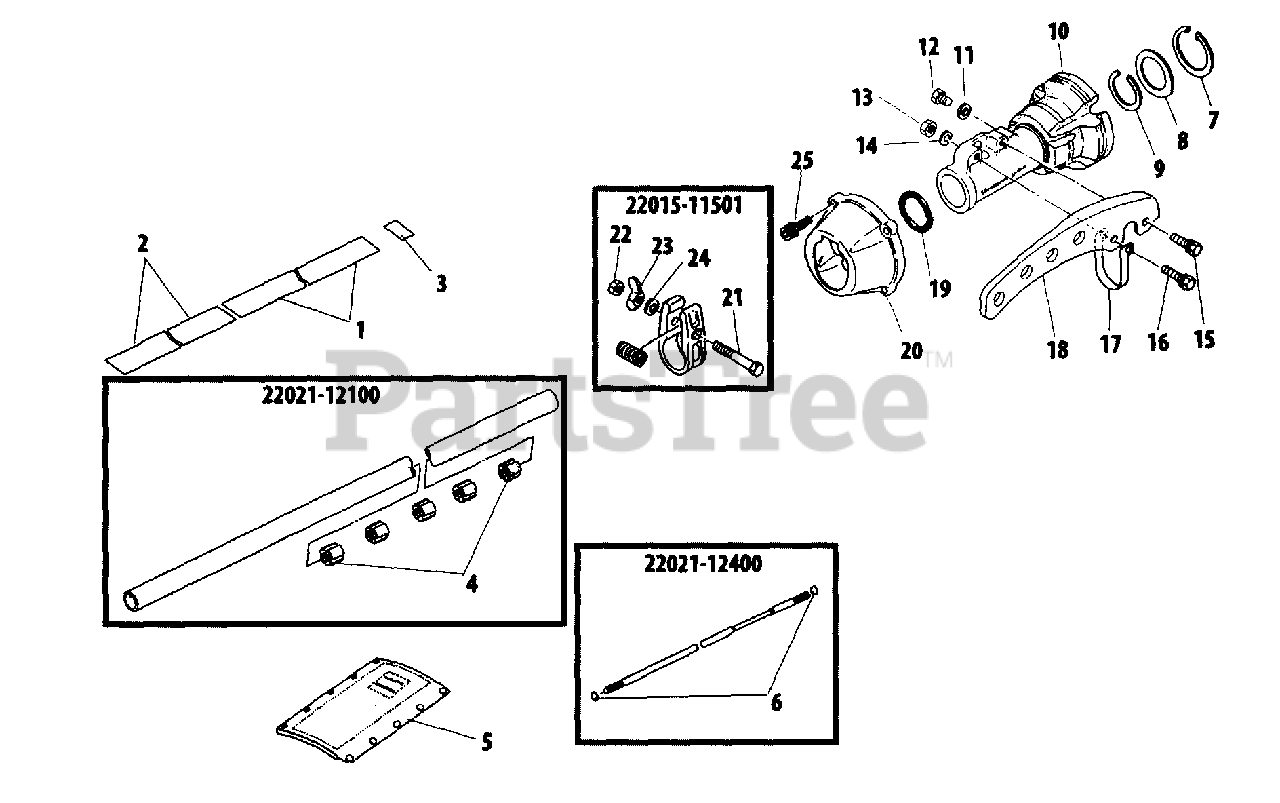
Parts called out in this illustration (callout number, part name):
1	LABEL - MODEL
2	LABEL, CAUTION
3	LABEL, HANDLE
4	BUSHING
5	PROTECTOR
6	STOPPER
7	RING, SNAP Ø40
8	STOPPER
9	RING, SNAP
10	CUSHION, AV
11	WASHER
12	BOLT M6×8
13	NUT, HEX M6
14	WASHER, SPRING 6
15	BOLT M6×16
16	BOLT M6×30
17	CLAMP
18	HANGER
19	O-RING
20	CAP, CUSHION
21	BOLT
22	NUT, LOCK M6
23	NUT, WING M6
24	WASHER 6 MM
25	BOLT M5×20
22015-11501	SWIVEL ASSY
22021-12100	MAIN PIPE ASSY
22021-12400	SHAFT ASSY, DRIVE
